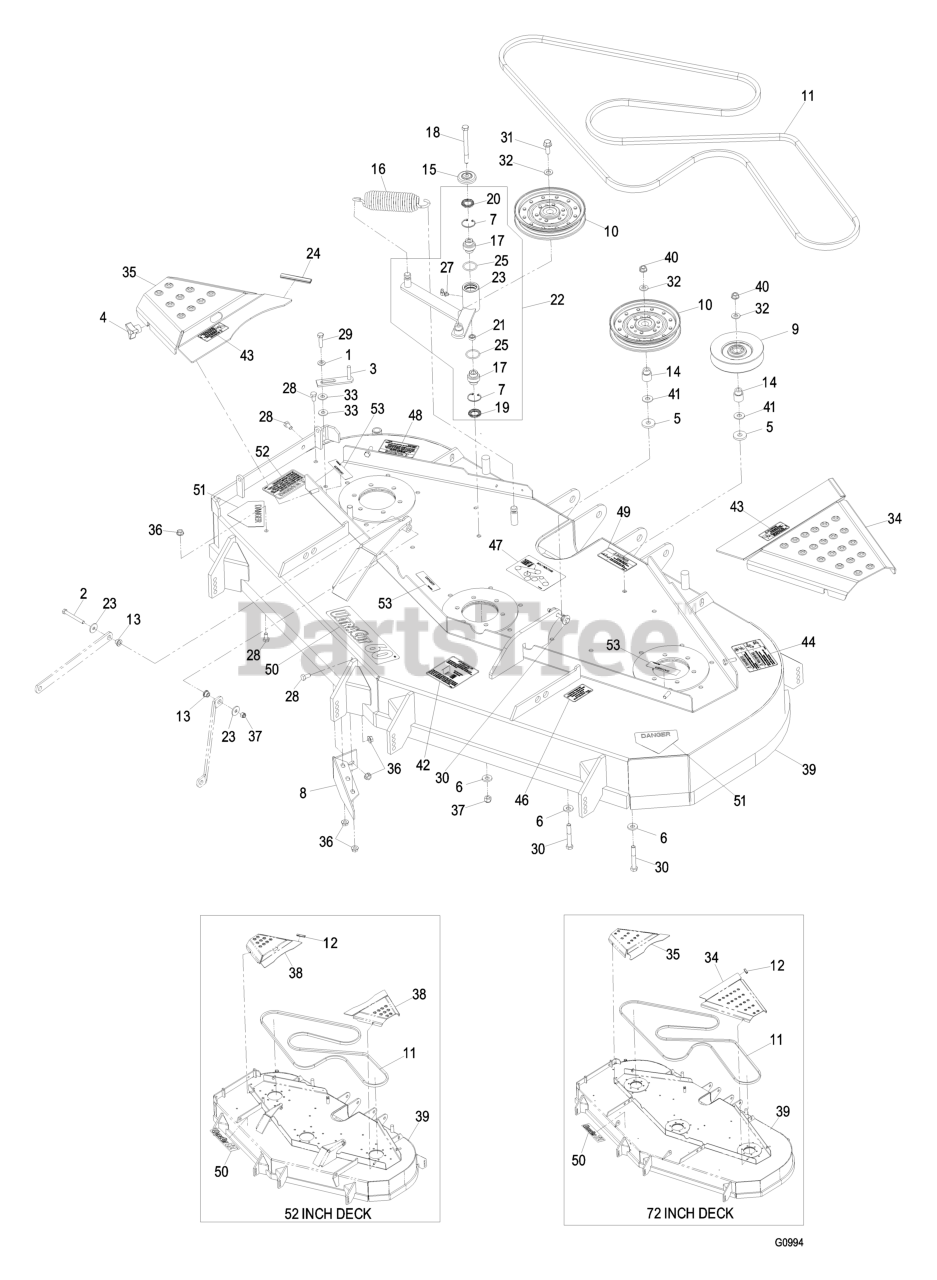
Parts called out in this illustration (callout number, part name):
1	WASHER-SPRING
2	SCREW-HH
3	GUIDE-BELT
4	KNOB-3 PRONG
6	WASHER-BELLEVILLE
7	RING-SNAP
8	WLD,BAFFLE DISCHARGE
9	PULLEY-IDLER
11	BELT,BLADE DRIVE 52
13	SPACER-STRUT
14	BUSHING-IDLER
15	GUARD-TOP
17	BEARING-SPHERICAL
18	SCREW-HH
19	SEAL-LIP, DOUBLE
20	SEAL-LIP, SINGLE
22	KIT,DECK IDLER LZ/XP
24	STRIP-SEAL
27	FITTING-GREASE, 90 DEG
28	SCREW-HH
29	SCREW-HH
30	BOLT-CARR
31	SCREW-HHF
32	WASHER-FLAT
33	WASHER-FLAT
34	ASM,BELT SHIELD W/DECAL L
35	ASM,BELT SHIELD W/DECAL R
37	NUT-LOCK, NI
38	ASM,BELT SHIELD W/DECAL
40	NUT-HHF, WHIZ
41	WASHER-FLAT
42	DECAL,ANTISCALP
43	DECAL,CRUSHING HAZARD
44	DECAL,DECK WARNING
46	DECAL,BOLT TORQUE
47	DECAL,BELT ROUTING
48	DECAL,CRUSHING HAZARD
49	DECAL-DRIVELINE
50	DECAL,ULTRACUT 52
51	DECAL-DANGER
52	DECAL-WARNING, DISCHARGE
53	DECAL-COVER, MISSING
54	ASM,FR524 DECK ASM W/DECA
